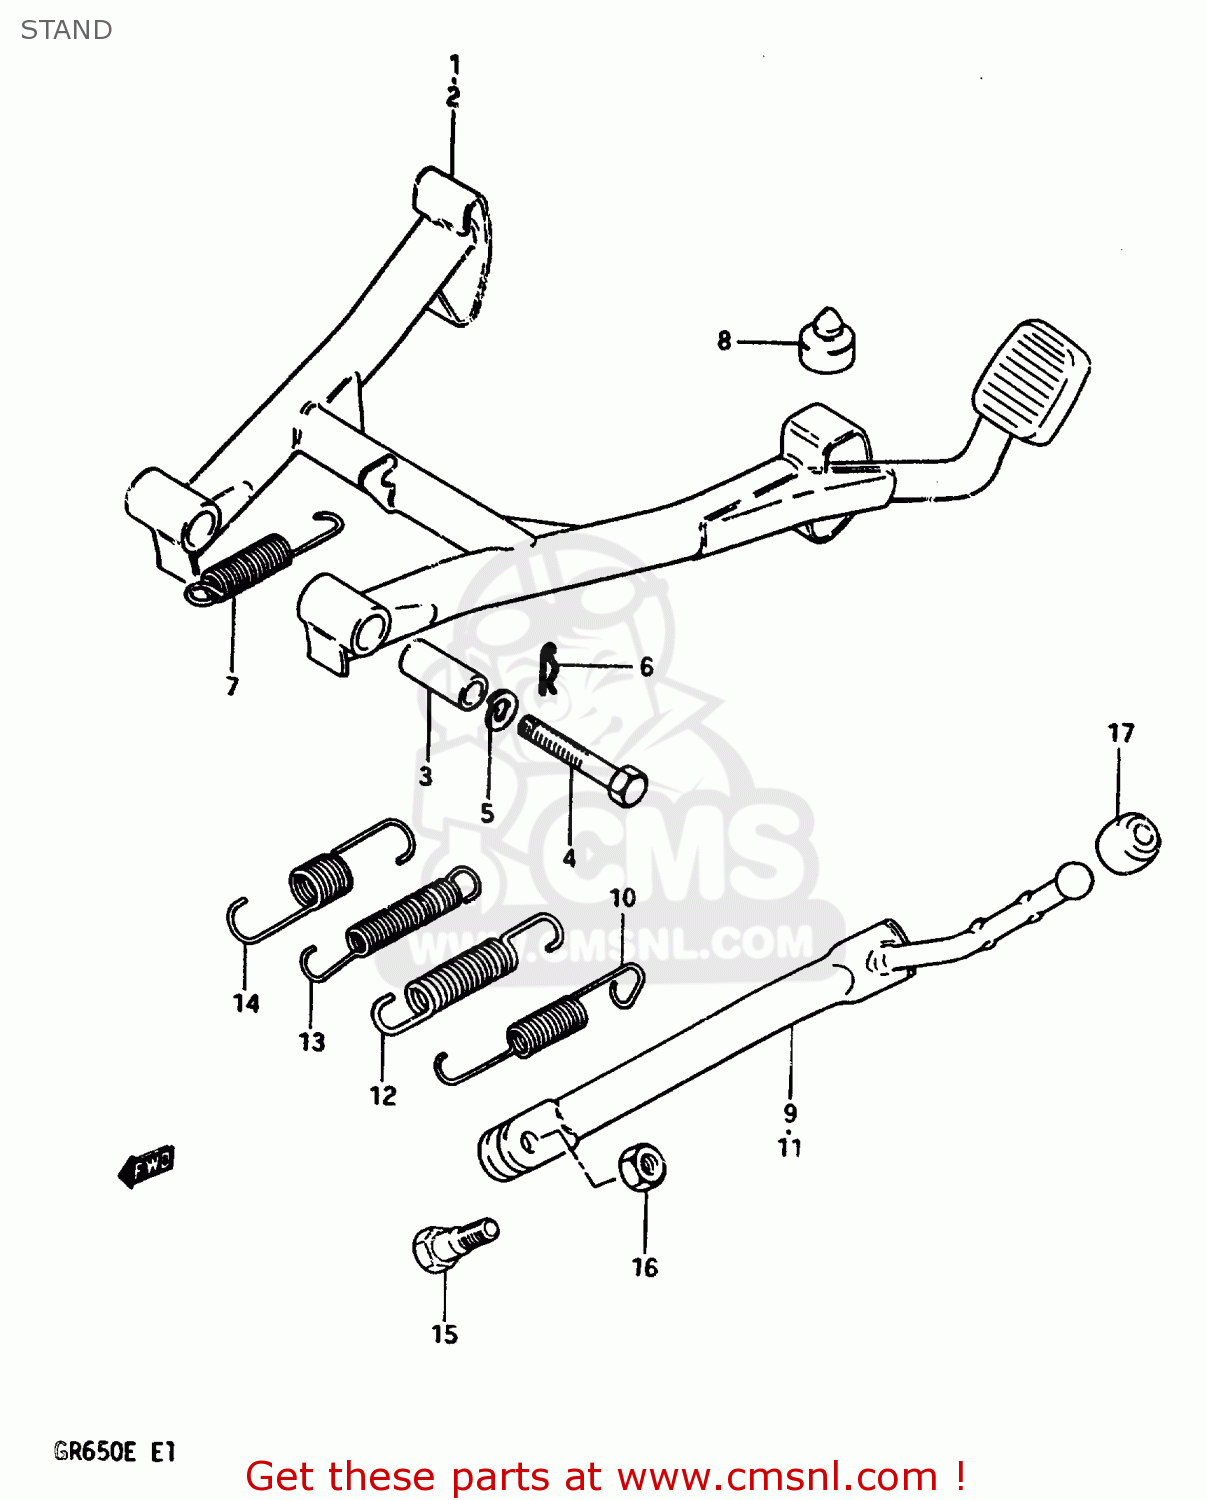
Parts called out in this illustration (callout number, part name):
1	STAND,CENTER
2	STAND, CENTER
3	SPACER(10X16X38.8)
4	BOLT
5	LOCK WASHER
6	CLIP
7	SPRING
8	CUSHION
9	STAND,SIDE
10	SPRING
11	STAND, PROP
12	SPRING
13	SPRING
14	SPRING, OUTER
15	BOLT L:30
16	NUTM10X1.25X8
17	CUSHION
